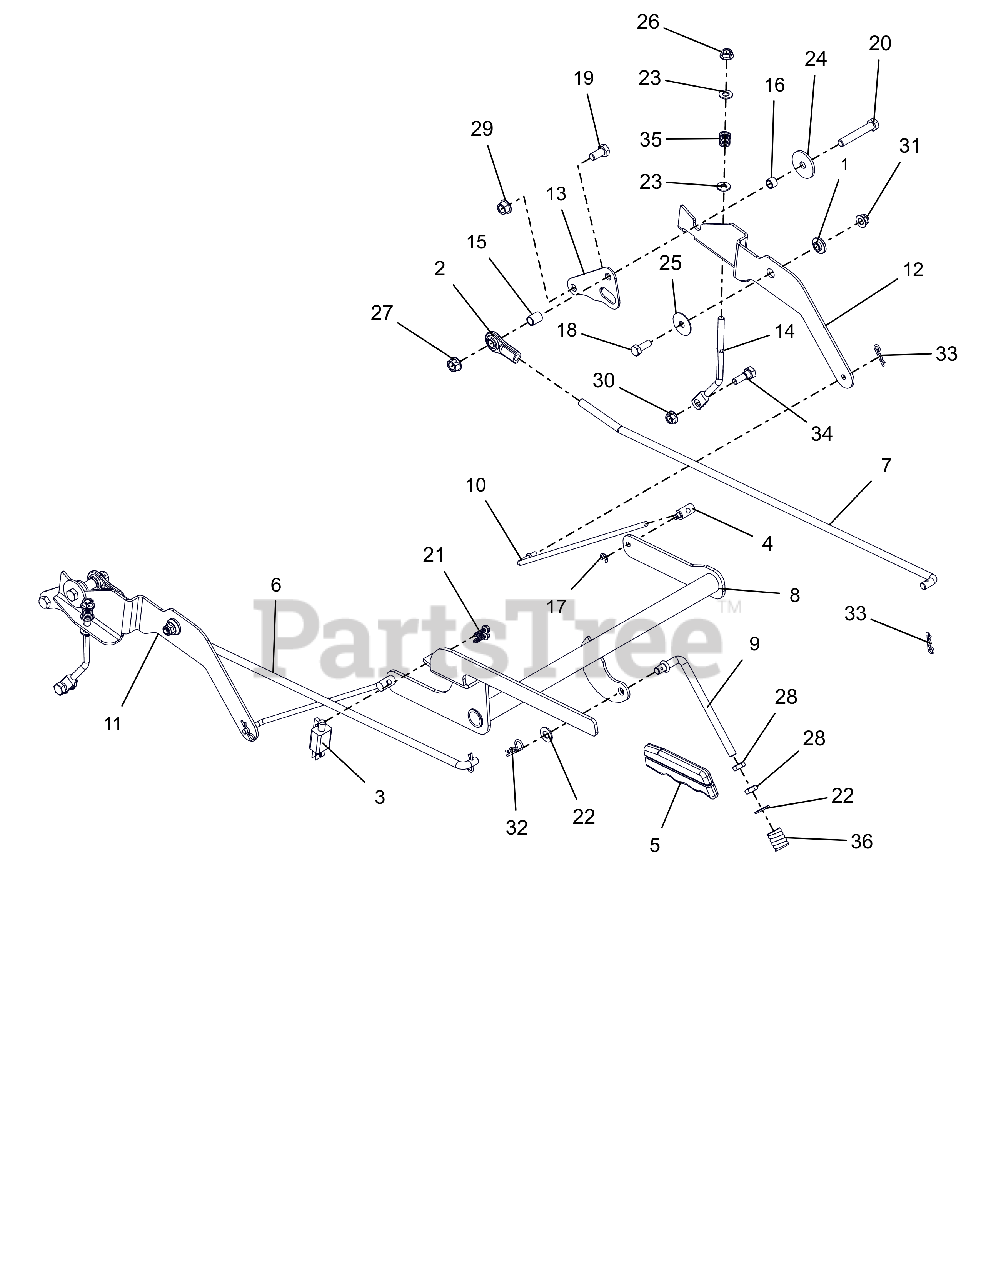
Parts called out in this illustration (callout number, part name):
1	BSHG, FLG .325X.499X.26X.88
2	ROD END, .38 RH
3	SWITCH- DOUBLE POLE N.O./N.O.
4	TRUNION, 1/4-20
5	GRIP, PARKING BRAKE (YELLOW)
6	STEERING, LINKAGE RH
7	STEERING, LINKAGE LH
8	WLDMT, BRAKE LEVER
9	LINK, OVER CENTER, PARKING BRK
10	LINK, BRAKE ARM
11	INTERLOCK, RH BRAKE LINK
12	INTERLOCK, LH BRAKE LINK
13	PLATE, TRANSAXLE ADAPTOR
14	LINK, BRAKE (XL)
15	SPCR, SLV .385X.500X.652
16	SPCR, SLV .385X.500X.350
17	RG-RTNG-EXT .250X.025
18	BOLT-HEX.31-18X.875 YWZC GR5
19	@BLT-HEX .38-16X.75 GR5 YWZC
20	@BLT-HEX .38-16X2.25 GR5 YWZC
21	SCR-TAP #12X.75 BOSS INDHXHD
22	@WSHR-FL-STL.406X.812X.065 YWZ
23	@WSHR-FL-STL.344X.688X.065YWZC
24	WSHR-FL-STL .380X1.50X.125YWZC
25	WSHR-FL-STL .347X1.254X.048YWZ
26	@NUT-LK-CTR-FLG .31-18 YZ GR F
27	NUT-LK-CTR-FLG .38-16 YWZC
28	NUT-HEX-JAM .375-16 YWZC
29	@NUT-LK-TOP-FLG .38-16 YWZC
30	@NUT-LK-TOP-FLG .31-18 YWZC
31	@NUT-LK-NYL-FLG .31-18 YWZC
32	PIN-HAIR CTR .09 X 1.50 YWZC
33	PIN-HAIR INT .08X.18X1.18 YWZC
34	BOLT,SHLDR .38X.25 -.31-18X.75
35	SPRING, COMPRESSION
36	SG-COMP .187X.56X1.62
